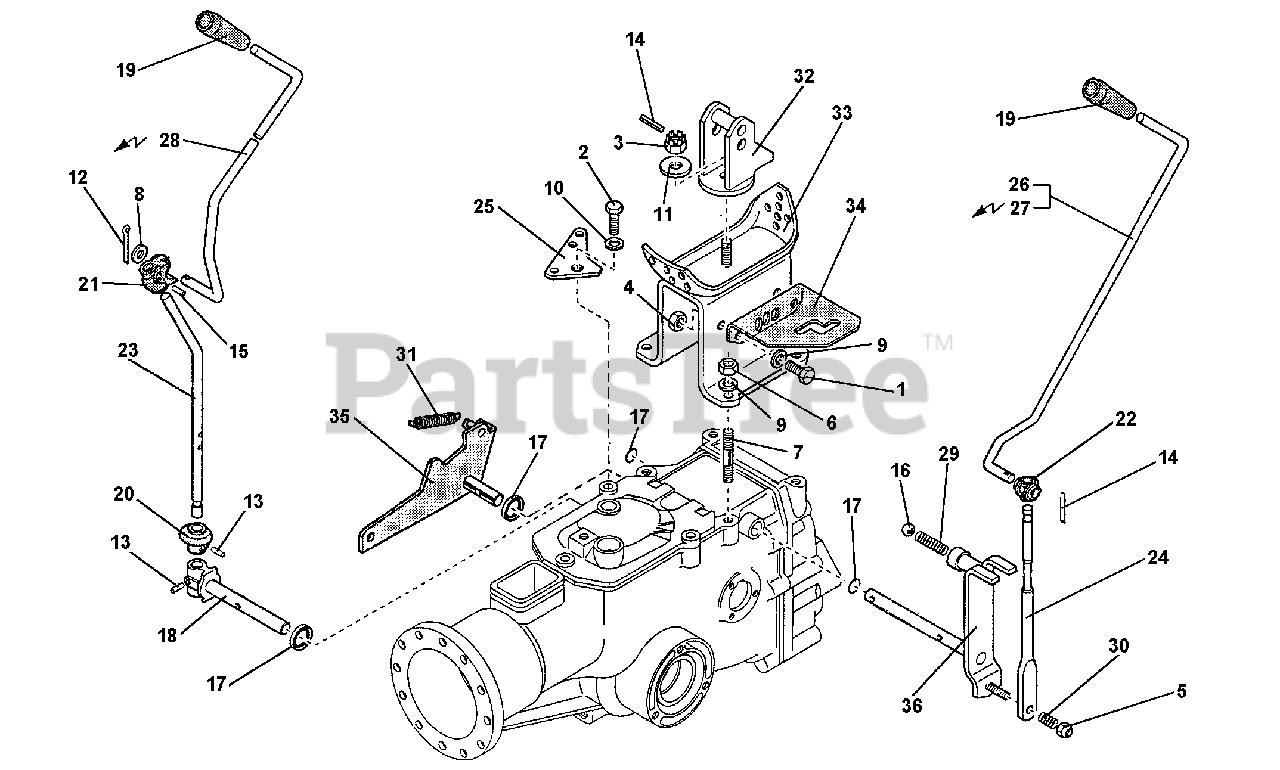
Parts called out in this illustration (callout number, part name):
1	SCREW, M8X20
2	SCREW, M8X30
3	NUT, CASTLE, M12
5	NUT, SELF LOCKING, M8
7	STUD, M8X38X14X20
8	WASHER, M10.5
9	SUPER WASHER
10	WASHER, LOCK, M8.4
11	LOCK WASHER, M13
13	PIN, LOCKING, M4X20
14	PIN, LOCKING, M3X22
15	PIN, LOCKING, M4X24
16	BALL, 15/32"
17	OIL SEAL, 14X22X4
20	PTO STOP RING
21	PTO ARTICULATION
22	SPEED ARTICULATION, 716, 720, 730
23	PTO CONTROL LEVER
24	SPEED CONTROL LEVER
25	REVERSE BRACKET
26	SPEED CONTROL ROD, RECOIL START
27	SPEED CONTROL ROD, ELECTRIC START
28	PTO CONTROL ROD, ELECTRIC START
32	HANDLE BAR SUPPORT
33	HANDLE BAR ANCHOR
34	GEAR SELECTOR, 716, 720, 730
35	REVERSE LEVER
36	SPEED CONTROL LEVER, 716, 720, 730
